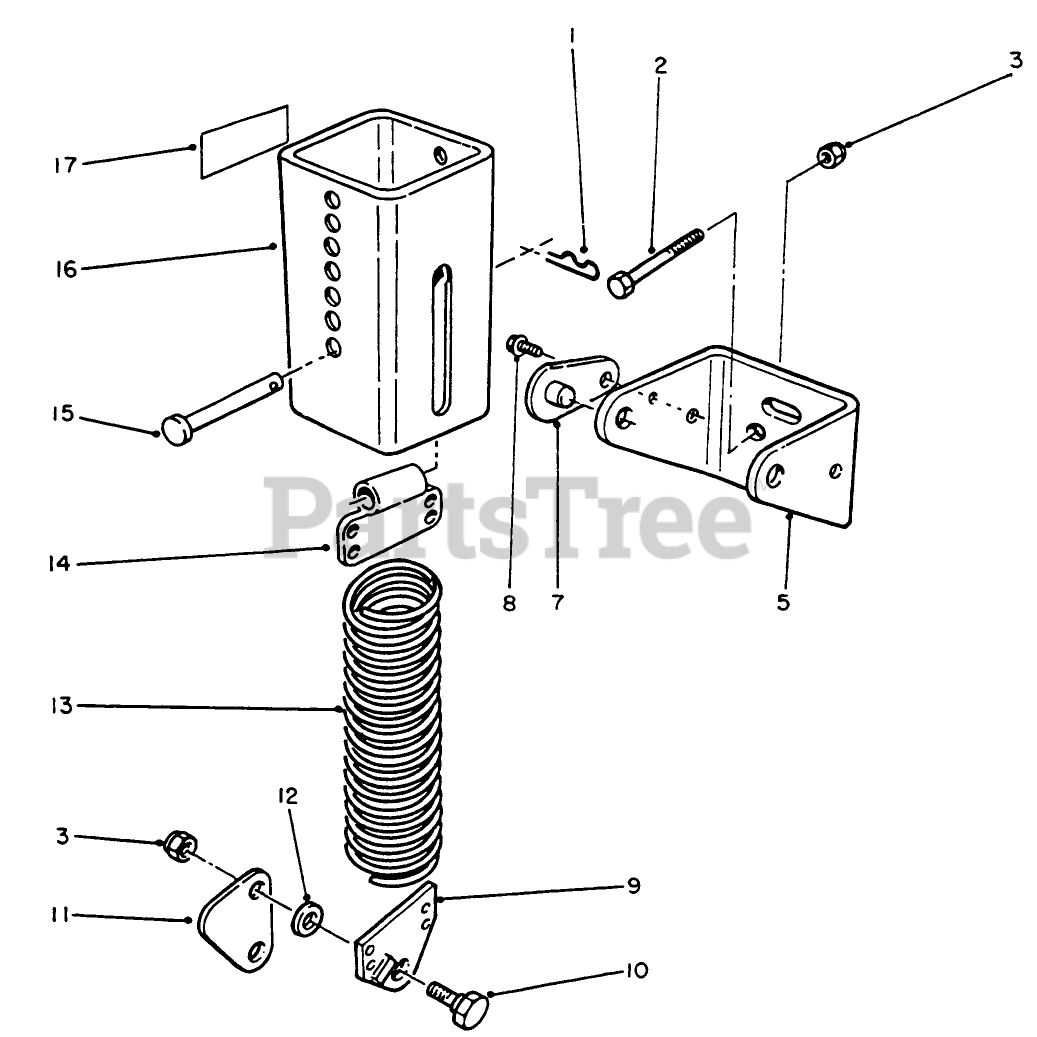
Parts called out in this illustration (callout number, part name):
1	PIN-HAIR
3	NUT-LOCK, NI
5	Bracket-Mounting
7	PIN-LOCK
8	SCREW
9	End Spring
10	BOLT-SHOULDER
11	Link Knee
12	WASHER-FLAT
13	Spring-Extension
14	End Spring
15	PIN-CLEVIS
16	Asm-Spring Cover
17	DECAL-WARNING
